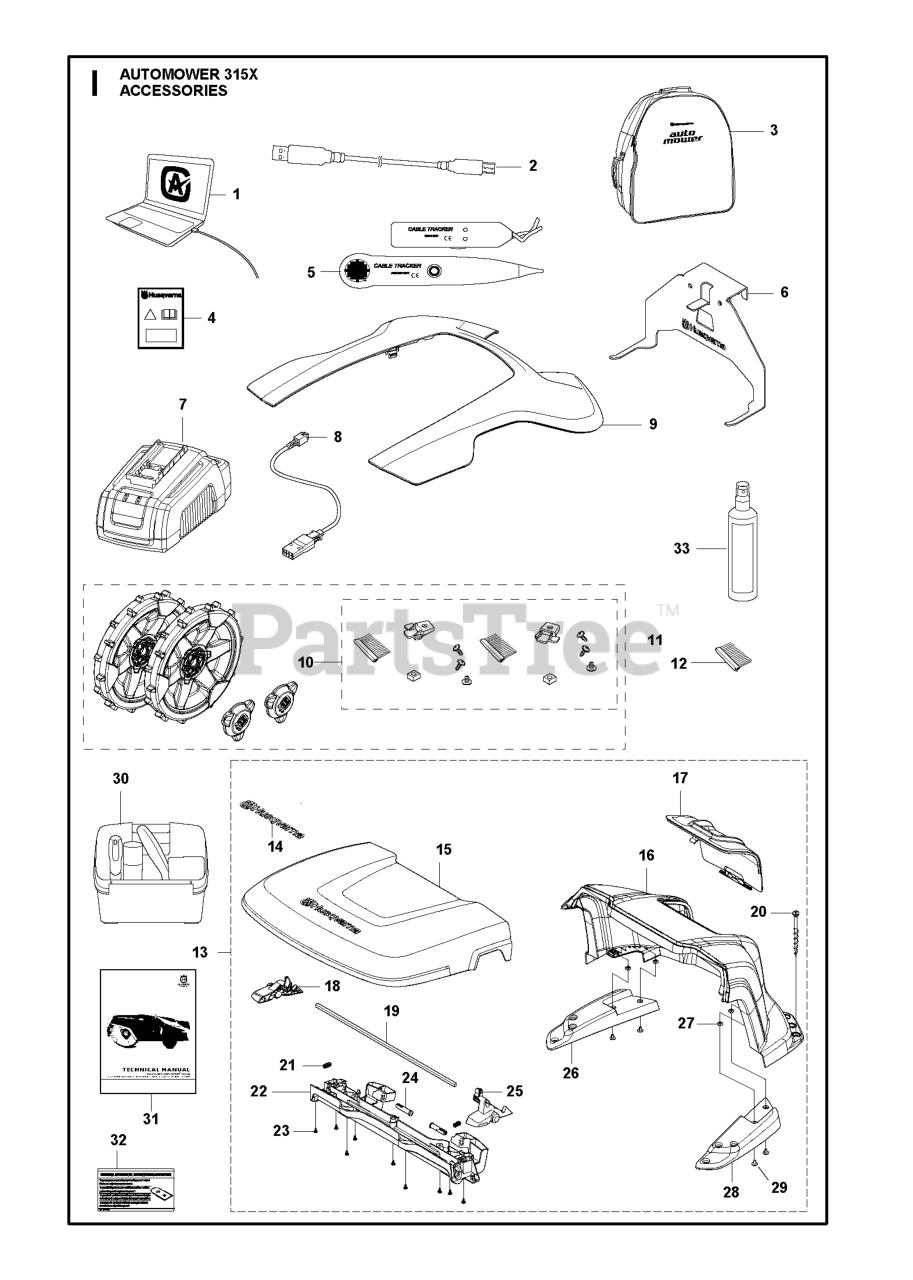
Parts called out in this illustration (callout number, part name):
2	CABLE WHITE ALT GREY
3	BAG
4	LABEL WARRANTY SEAL DEALER
5	TEST EQUIPMENT
6	315 WALL HANGER
7	CHARGER BATTERY TEST
8	CABLE ASSY QUICK CHARGER
9	BODY KIT GREY 315X
9	BODY KIT WHITE 315X
10	WHEEL BRUSH KIT 315
11	WHEEL KIT AM310/315. HEAVY REA
12	BRUSH WITH CARTON
13	HOUSE KIT FOR 315
14	DECAL.HUSQVARNA.210MM
15	COVER LID 315
16	COVER BASE P15
17	HATCH
18	HANDLE RELEASE LEFT
19	ROD
20	SCREW KIT CS
21	SPRING SPRING CAP
22	BEAM
23	SCREW 14MM
24	HINGE PIN
25	HANDLE RELEASE RIGHT
26	SUPPORT BASE LEFT
27	NUT
28	SUPPORT BASE RIGHT
29	SCREW IHPANM M6X25 4.6 ZP-BC
30	CLEANING AND MAITENANCE KIT AM
32	DECAL WARNING ORIGINAL BLADE E
32	ORIGINAL PARTS STICKER
33	AUTOMOWER ACCY
